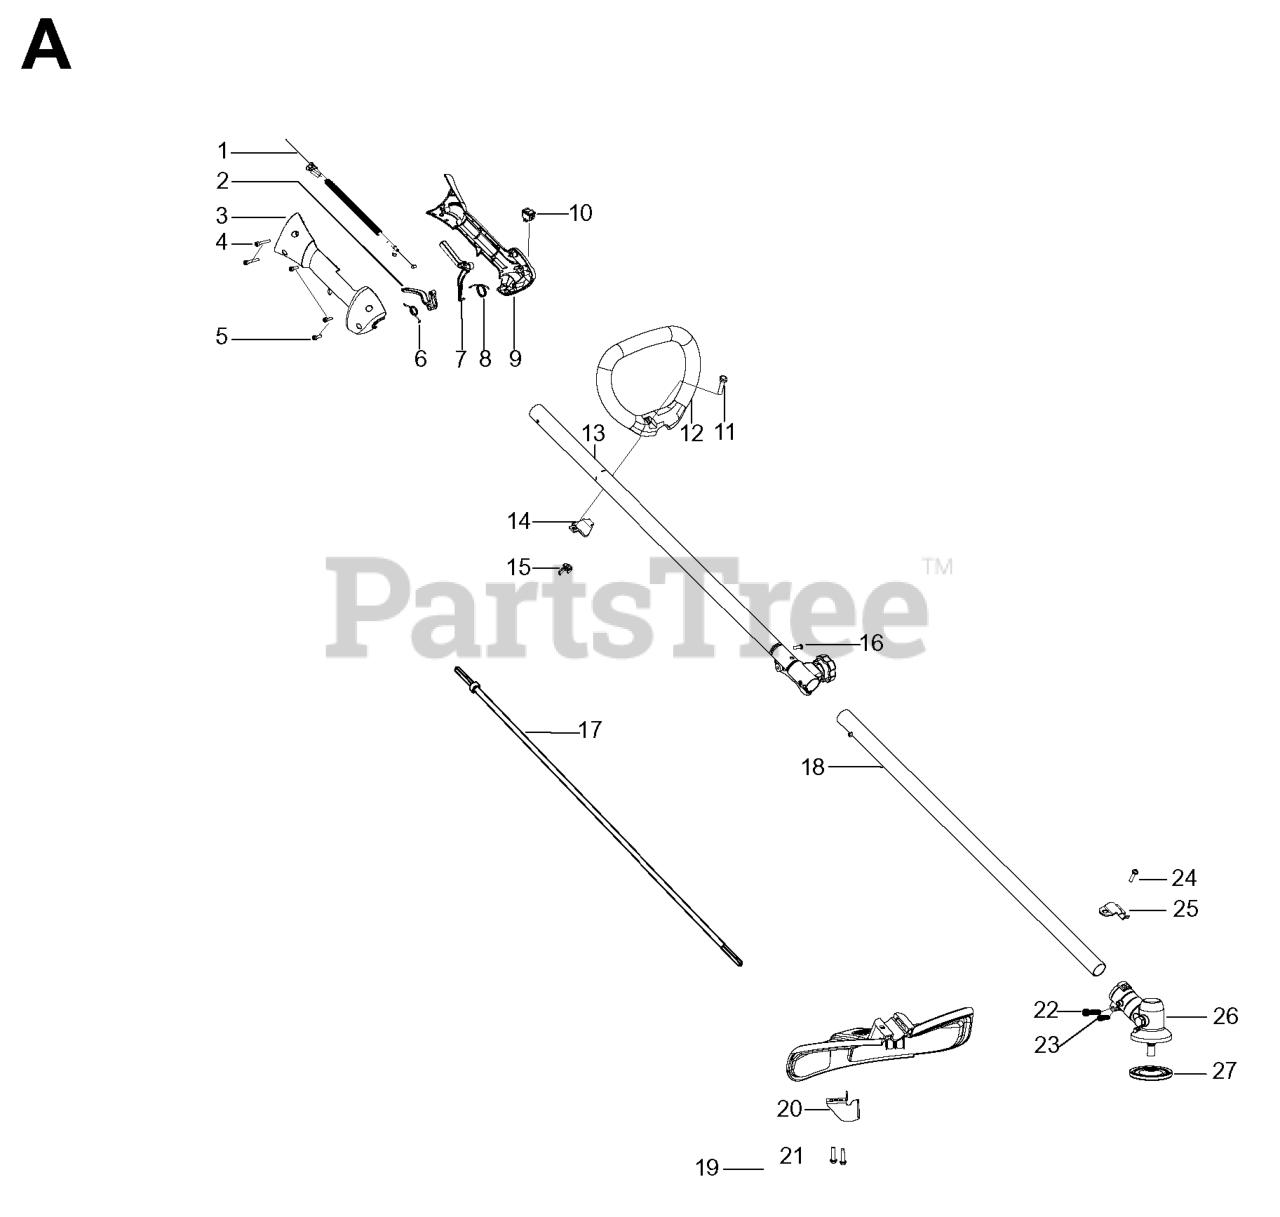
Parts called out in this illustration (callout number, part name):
1	%ASSY CABLE WIRE HARNESS
2	TRIGGER THROTTLE
3	HOUSING-THROTTLE RH
5	SCREW M4 X 1.75 PT 16MM
6	SPRING TRIGGER
7	THROTTLE LOCKOUT
8	SPRING LOCKOUT
9	HSG THROTTLE LH
10	KIT SWITCH
11	BOLT, TYPE 2
13	KIT-DRIVESHAFT UPPER INC DECAL
14	CLAMP ASSIST HANDLE
15	WINGNUT, TYPE 2
17	FLEX-LOWER
18	HSG DRIVESHAFT LOWER
19	KIT COBI SHIELD
20	Limiter - Line
22	SCREW - CARB. ADAPTOR
24	SCREW 1/4-20 X 7/8 (TAP
25	BRACKET SHIELD STRAIGHT SHAFT
26	ASSY GEARBOX
27	ASSY DUST CUP
545059001	DECAL-WARNING
